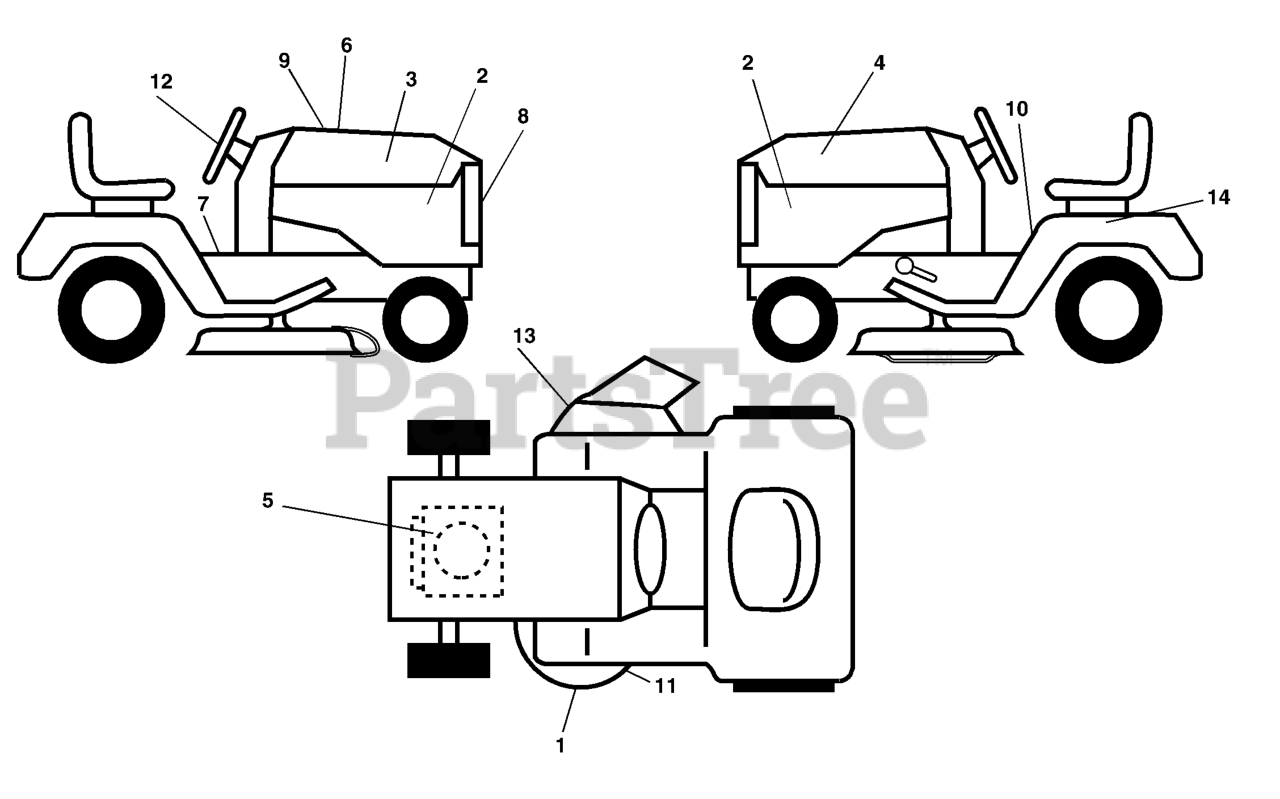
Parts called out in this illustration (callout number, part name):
1	DECAL, MOWER HEAVY DUTY
2	HOOD DECAL, YTH2148
3	DECAL, HOOD RH
4	DECAL, HOOD LH
6	DECAL HOOD CUST. RESP.
9	DECAL.RPLM.YTH2148
10	DECAL FENDER DANGER
11	DECAL V-BELT SCHEMATIC
12	DECAL.STEERING.HUSQ.BLUE
13	DECAL.WARN.KEEP.HAND.AWAY
14	DECAL BTRY SYMBOLS
